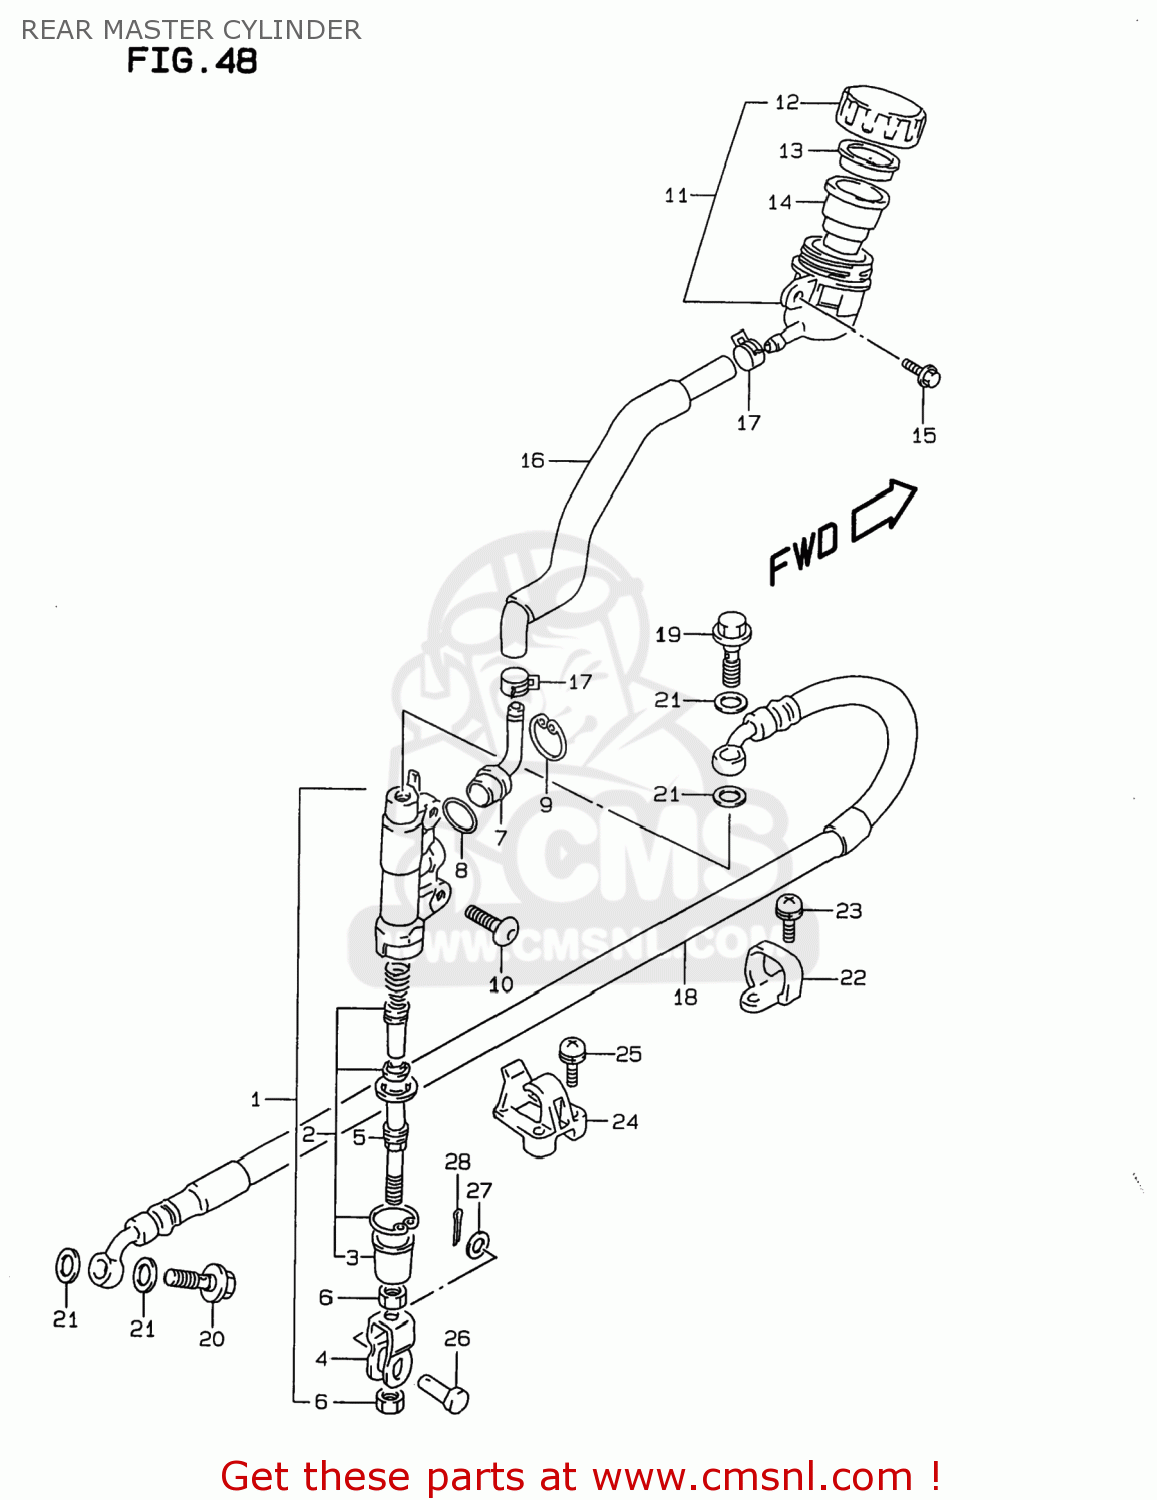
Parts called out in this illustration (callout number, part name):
1	CYLINDER ASSY,RR MASTER
2	PISTON/CUP SET
3	BOOT
4	YOKE
5	ROD,PUSH
6	NUT
7	CONNECTOR
8	O RING
9	CIRCLIP
10	SCREW(6X16)
11	TANK ASSY,RR BRAKE RESERVOIR
12	CAP
13	PLATE
14	DIAPHRAGM
15	BOLT
16	HOSE COMP,RESERVOIR TANK
17	CLIP
18	HOSE,RR BRAKE
19	BOLT UNION
20	BOLT UNION
21	WASHER(10X15X1.5)
22	GUIDE,RR BRAKE HOSE
23	SCREW
24	GUIDE,RR BRAKE HOSE
25	SCREW
26	PIN(8X20)
27	WASHER(8.5X13X1.6)
28	PIN 20X15
